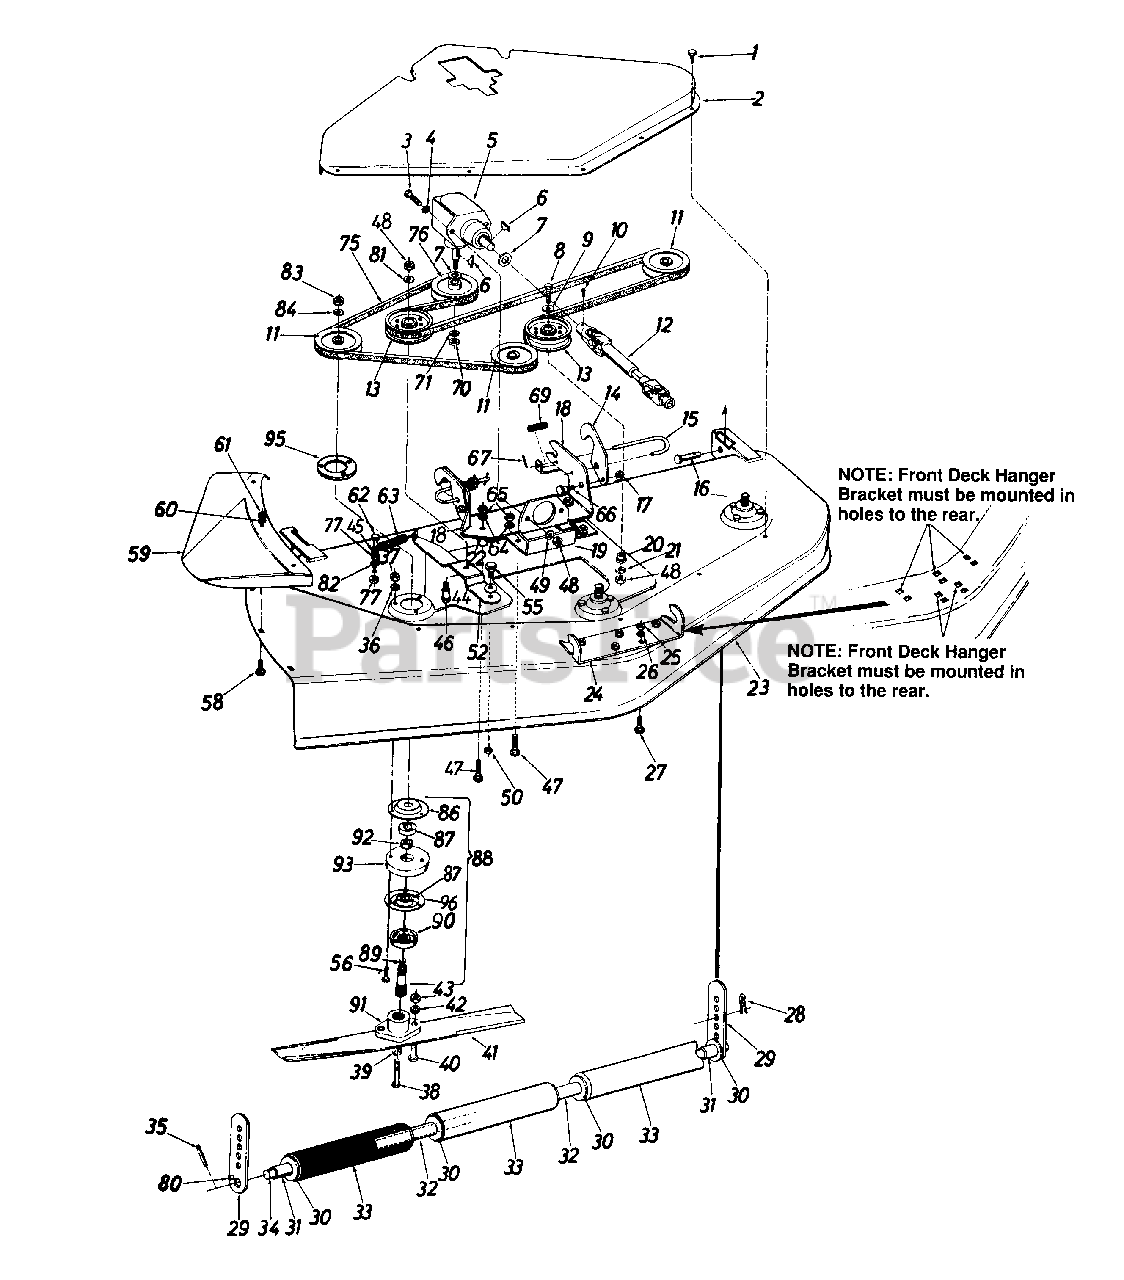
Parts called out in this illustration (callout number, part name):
1	Hex B-Tap Scr. 1/4-20 x .38" Lg.
4	Ext. L-Wash. 3/8" I.D.
5	Right Angle Drive
6	#9 Hi-Pro Key 3/16 x 3/4" Dia.
7	Fl-Wash. 29/32" I.D.
8	Hex Bolt 3/8-16 x 2.25" Lg.
9	Fl-Wash. 3/8" I.D.
10	Sq. Hd. Set Scr. 3/8-16 x .50"
12	Universal Drive Shaft Ass'y.
13	Deck Idler Pulley
14	Hanger Lock
16	Clevis Pin .50" Dia.
17	Hex L-Nut 5/16-18 Thd.
21	L-Wash. 3/8" I.D.
22	Spacer .33" I.D. x .88" O.D.
26	L-Wash. 5/16" I.D.
27	Carriage Bolt 5/16-18 x .75" Lg.
28	Internal Cotter Pin
30	Fl-Wash. .75" I.D. x 1.5" O.D.
31	Spacer .758" I.D. x 1.25" O.D. x .530
34	Roller Shaft
35	Roll Pin 3/16 x 1.25"
36	L-Wash. 5/16" I.D.
38	Hex Self-Tap Scr. 3/8-24 x .75" Lg.
39	L-Wash. 3/8" I.D. H.D.
40	Hex Bolt 5/16-24 x 1" Lg.
41	Blade 17"
42	L-Wash. 5/16" I.D.
43	Hex L-Nut 5/16-24 Thd.
44	Spr. Wash. .445" I.D.
45	Fl-Wash. 1/4" I.D.
46	Shld. Scr. .625" Dia. x .96"
47	Carriage Bolt 5/16-18 x 1.5" Lg.
48	Hex Nut 3/8-16 Thd.
49	L-Wash. 3/8" I.D.
50	Hex L-Nut 7/16-14 Thd.
56	Hex Bolt 5/16-24 x 1.5" Lg. (Grade 5)
58	Carriage Bolt 5/16-18 x .75" Lg.
60	L-Wash. 5/16" I.D.
61	Hex Nut 5/16-18 Thd.
62	Hex Bolt 1/4-28 x 1-3/4" Lg.
63	Extension Spring
64	L-Wash. 5/16" I.D.
65	Hex Nut 5/16-18 Thd.
67	Roll Pin 1/8" Dia.
69	Compression Spring
70	Hex L-Nut 5/8-18 Thd.
71	L-Wash. 5/8" I.D.
75	"V"-Belt
76	Drive Pulley
77	Hex L-Nut 1/4-28 Thd.
80	Spring Pin Spiral 1/4" Dia. 1.00" Lg.
81	Bell-Wash. 3/8" I.D. x .87" O.D.
82	L-Wash. 1/4" I.D.
83	Hex Jam Nut 5/8-18 Thd.
84	L-Wash. 5/8" I.D.
86	Bearing Housing
87	Ball Bearing
88	Deck Spindle Ass'y.
89	Spindle
90	Bearing Shield
91	Blade Adapter
95	Spindle Reinforcement Plate
96	Open Bearing Housing
12649-0638	GUARD-CHUTE - MTD/TROY-BILT RED (0638)
12649-0648	GUARD-CHUTE - TECH GRAY (0648)
12649-0650	GUARD-CHUTE - RED METALLIC (0650)
12649-0662	GUARD-CHUTE - OYSTER GRAY (0662)
12650-4008	Height Adjuster - WINE RED (4008)
